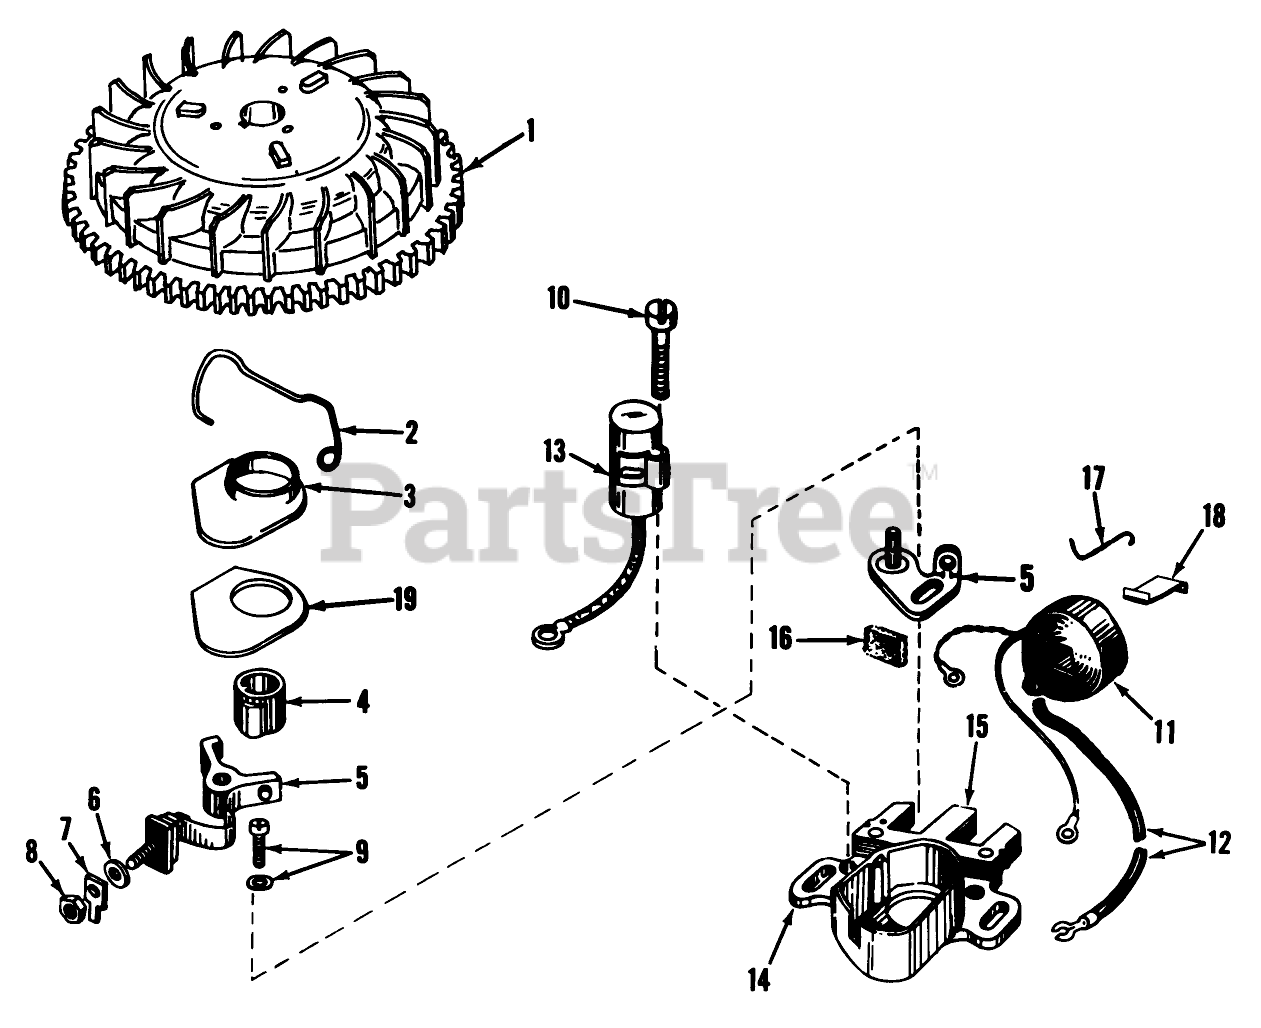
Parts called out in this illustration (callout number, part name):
1	FIywheel
2	Spring Breaker Box
3	Cover, Dust
4	Cam, Breaker
5	Breaker Assy.
6	Washer
7	Terminal
8	DECAL
9	Breaker Screw
10	Condenser Screw
11	Coil Assy., (Inc. Ref. Nos. 12, 13 18)
12	Wire, Lead
13	Condenser
14	Core Plate
15	Stator Assy., (Incl. Nos. 2, 3, 5 thru 14 16 thru 19)
16	Felt,Cam Wiper
17	Clip, Coil
18	Spring Coil Wedge
19	Gasket Dust Cover
